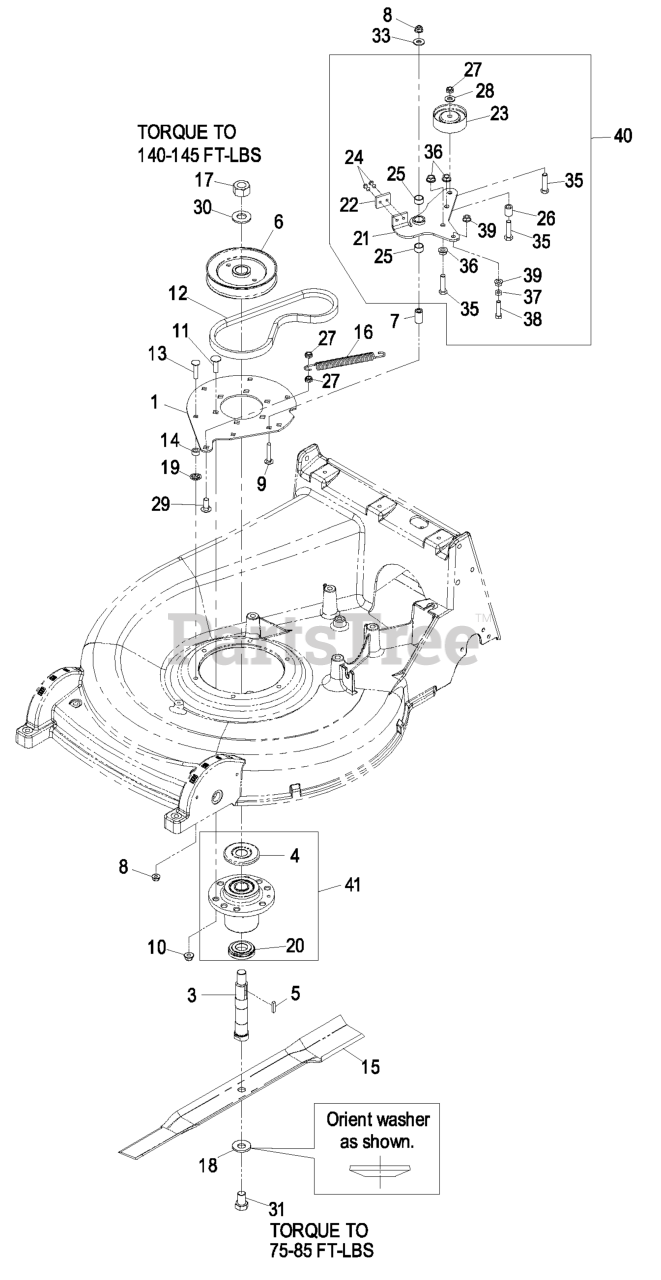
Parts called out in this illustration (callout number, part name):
1	PLATE-ADAPTER, HOUSING
3	SHAFT-SPINDLE
4	GUARD-BEARING, TOP
5	KEY-RECTANGLE
6	SHEAVE-SPLIT, STEEL (W/HU
7	BUSHING-ARM, IDLER
8	NUT-HF, NI
9	SCREW-CARR
10	NUT-HF, NI
11	Bolt-Carriage 3/8-16 X 1 1/4
12	BELT
13	BOLT-CARR
14	SPACER
16	SPRING-BRAKE
18	WASHER-SPRING
19	RING-RETAINING
20	SPACER-GUARD, BOTTOM
21	ASM,IDLER ARM W/BSHGS
22	PAD-BRAKE
23	PULLEY-IDLER
24	RIVET-POP
25	BEARING
26	BUSHING-LEVER, LIFT
28	WASHER-FLAT
29	SCREW-CARR
31	SCREW-CAP
33	WASHER-FLAT
35	SCREW-HH
36	NUT-HHF, WHIZ
37	NUT-JAM
38	SCREW-HH
40	IDLER ARM ASM
41	KIT, CUTTER HOUSING
42	ASM,CUTTER HOUSING COMPLE
